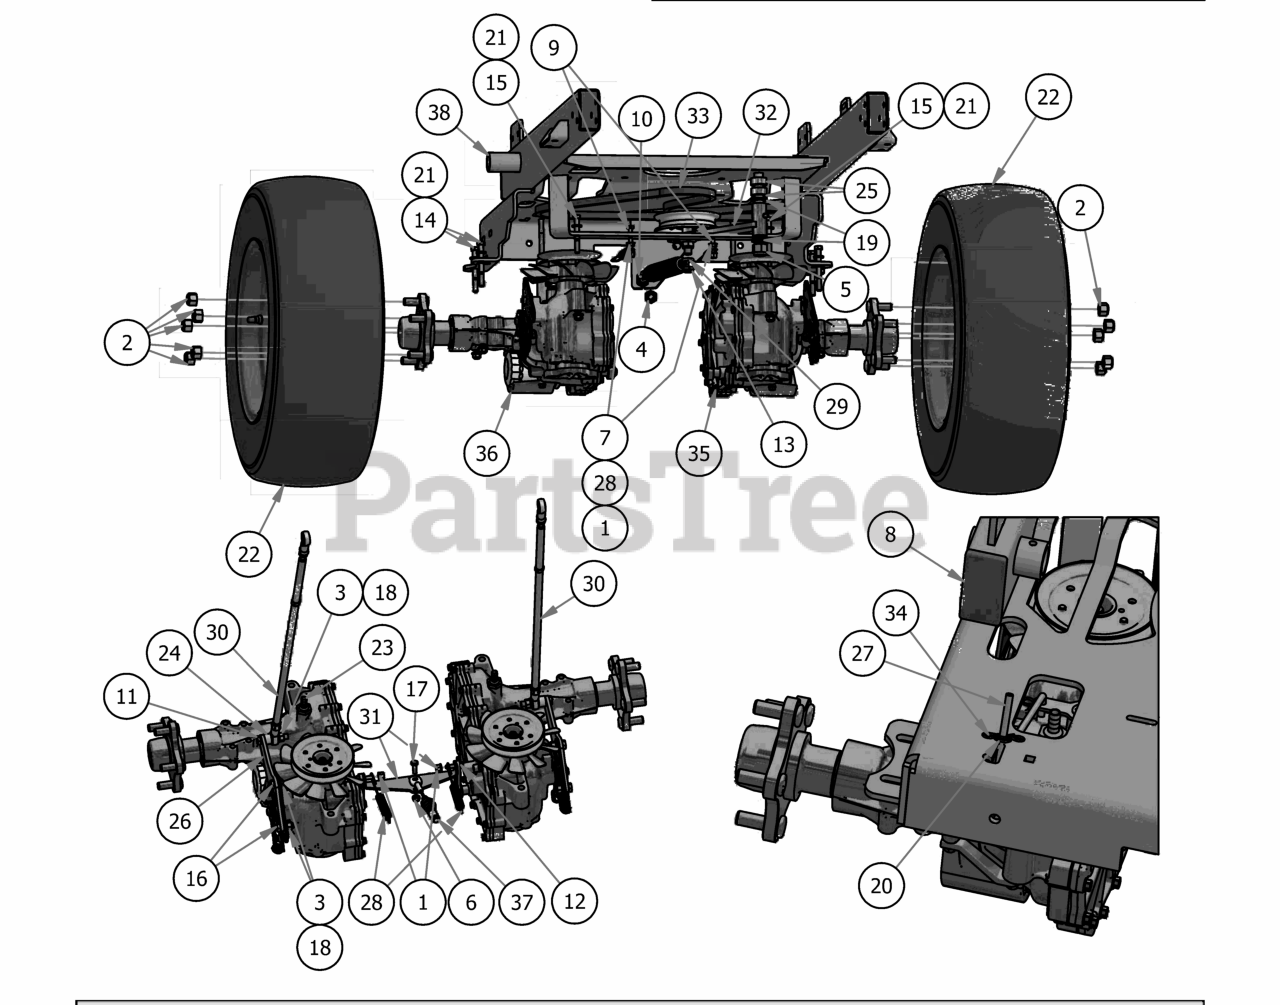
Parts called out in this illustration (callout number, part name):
1	1/4-20 Nylon Insert flange Nut
2	Acorn Lug Nut
3	3/8" Hex Nut
4	1/2" Hex Nut
5	5/8 Std NC Nylock Nut
6	1/4" Nylock Nut
7	1/4-20 Hex Flange Nuts Zinc w/Serrations
8	1 1/2 x 3 Frame Plug
9	1/4-20 x 2 Hex Bolt
10	All Thread-Pump Idler Tensioner
11	3/8"-16 x 2" Gr 5 Hex Bolt
12	1/4-20 x 1 GR 5 hex bolt zinc
13	1/2" Nylcock Nut (1/2 Jam)
14	5/16" x 3" Hex Bolt
15	5/16" x 2 1/2" Bolt
16	3/8" x 1" Hex Bolt
17	1/4" x 3/4" Hex Bolt
18	3/8" Lock Washer
19	.630 ID Plastic Washer
20	1/4" Flat Washer
21	5/16" Flat Washer
22	23x9-12 Reaper Turf Tire & Wheel Assembly
23	45 degree fitting
24	ACS Spacer 3/4x3/8x1/2
25	5/8" x 1/" Collar W/One Set Screw
26	Stand On Control Arm Plate
27	2019 Stand On Neutral Rod
28	Brake Spring
29	Deck Idler Spring
30	2019 Stand On Drive Push Rod Assembly
31	Brake Bracket
32	2019 Stand On Idler Assembly
33	2019 Stand On Pump Belt (Timken# 47-2827)
35	Left 3400 IZT
36	Right 3400 IZT
37	Brake Cable
38	2019 Stand On Frame Weldment
